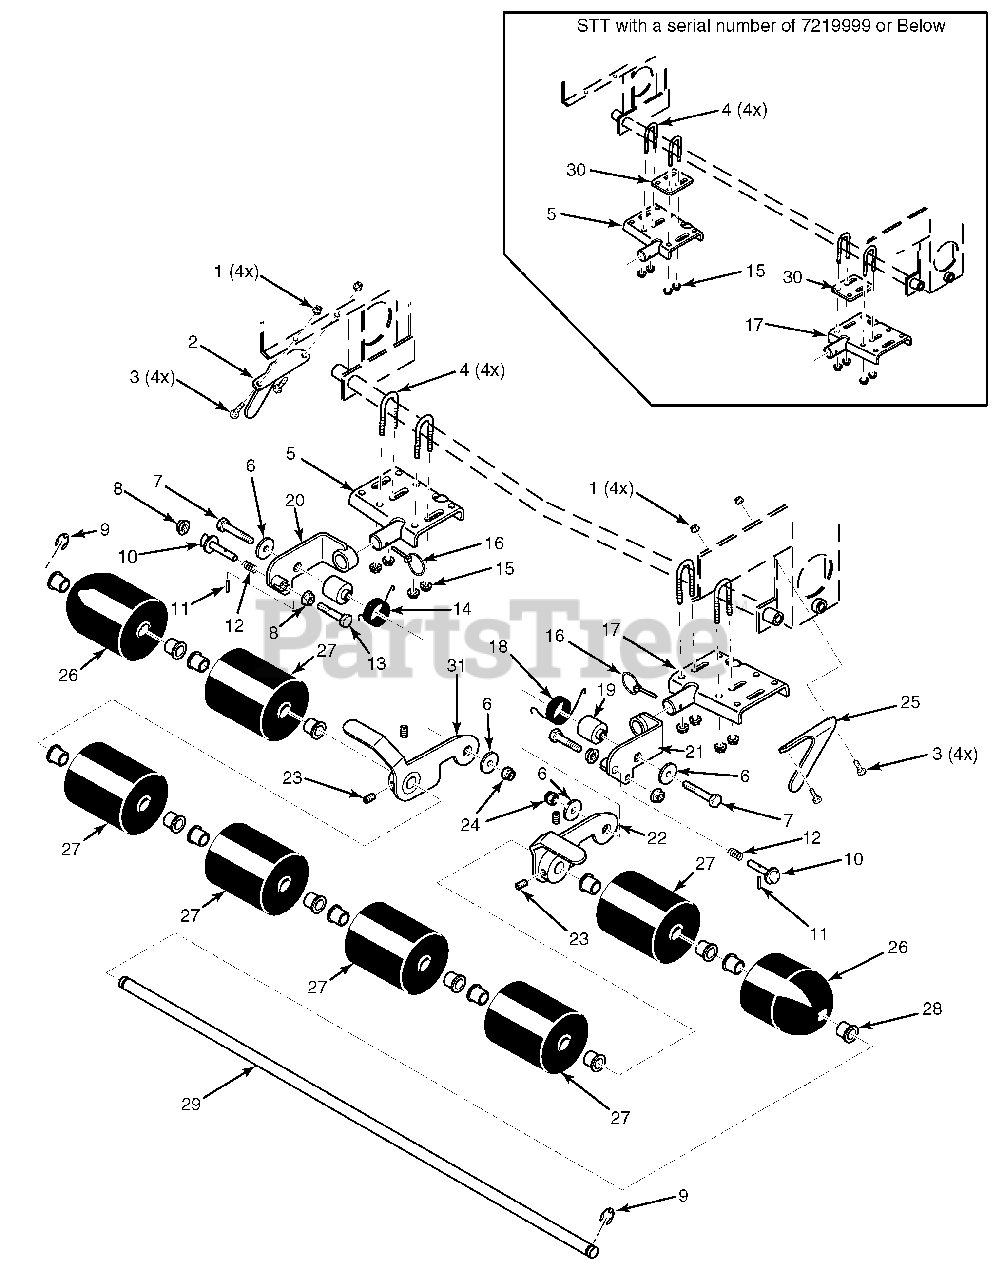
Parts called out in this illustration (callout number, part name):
1	Nut, Elastic Stop 3/8-16
2	Striper Stop, L.H. - STT Only
3	Bolt, Hex Head 3/8-16 x 1"
4	U-Bolt, 5/16-18 x 1"
5	Mounting Bracket Weldment, LH.
6	Flatwasher, 3/8-.406 x 1-1/2" 7 Gauge
7	Bolt, Hex Head 3/8-16 x 2-3/4"
8	Nut, Serrated Flange 3/8-16
9	Retaining Ring, .750 External "E"
10	Pin, Lift Latch
11	Pin, Slotted Spring .156 x 3/4"
12	Spring, Lock Pin
13	Bolt, Hex Head 3/8-16 x 2-1/2"
14	Spring, Torsion L.H.
15	Nut, Serrated Flange 5/16-18
16	Quick Pin, .188 Dia.
17	Mounting Bracket Weldment, R.H.
18	Spring, Torsion R.H.
19	Hub, Striper
20	Pivot Weldment, L.H.
21	Pivot Weldment, R.H.
22	Hinge Weldment, R.H.
23	Set Screw, 3/8-16 x 1/2"
24	Nut, Elastic Stop 3/8-16
25	Striper Stop, R.H. - STT Only
26	Roller Assembly, Striper End
27	Roller Assembly
28	Bushing, .752 Oilite
29	Roller Shaft
30	Spacer, Striper Mounting
31	Hinge Weldment, L.H.
